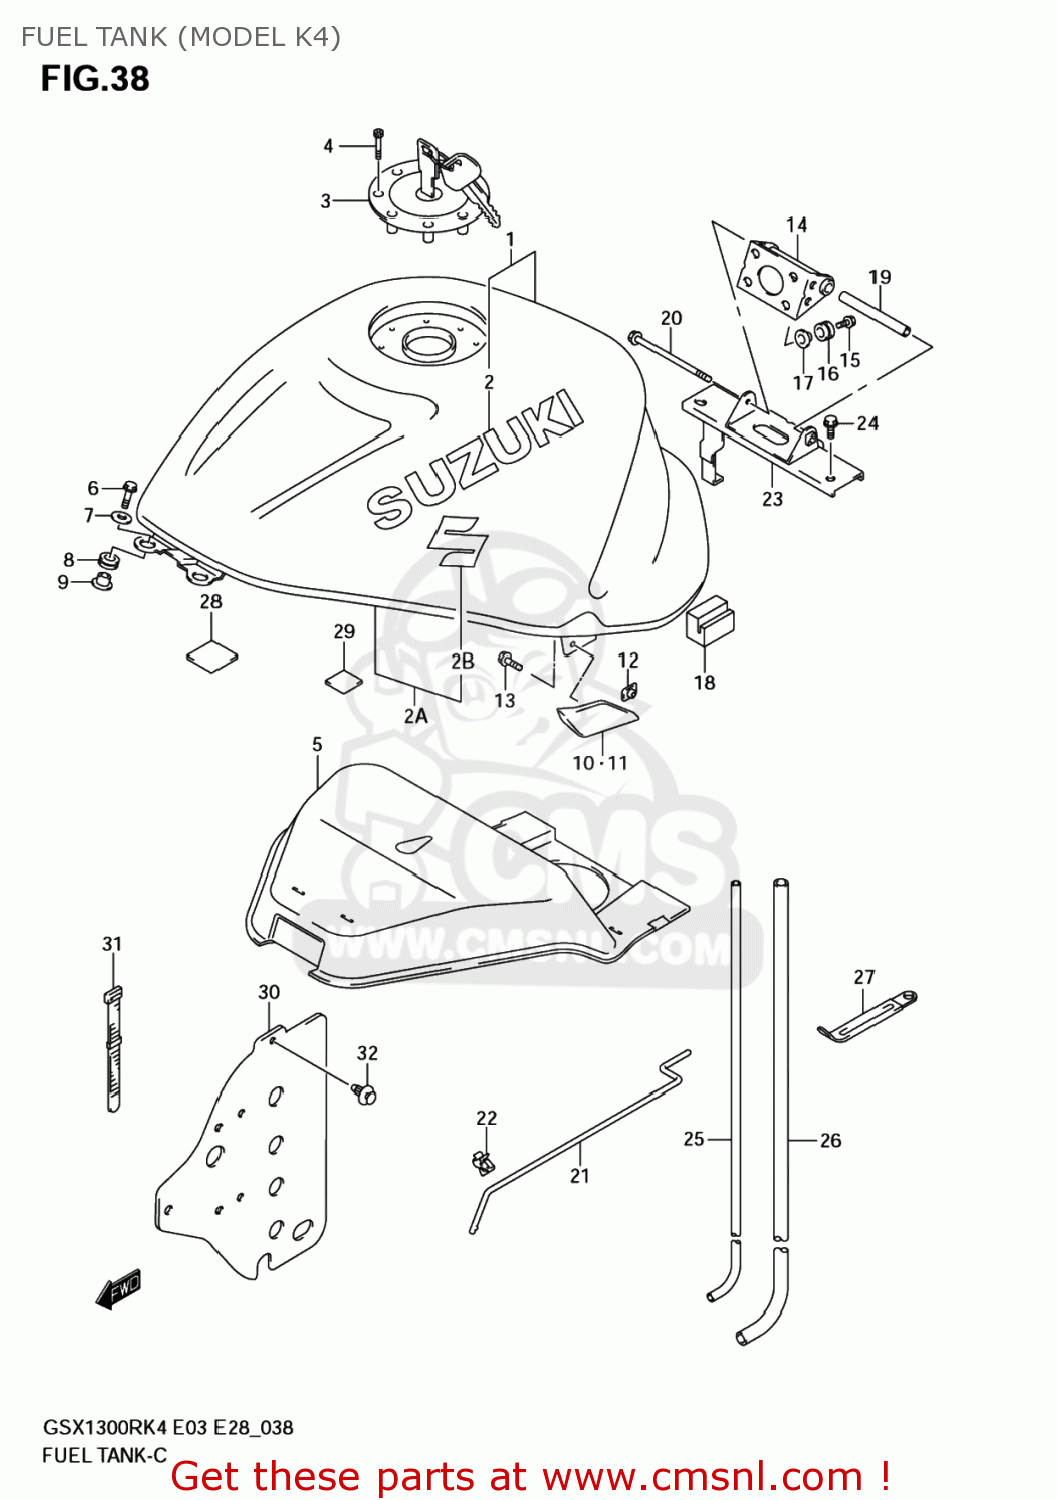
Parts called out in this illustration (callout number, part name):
1	TANK ASSY,FUEL
2	EMBLEM,FUEL TANK
2A	TANK ASSY,FUEL(RED)
2B	EMBLEM,S
3	CAP SET,FUEL TANK
4	BOLT(5X20)
5	SHIELD,FUEL TANK HEAT
6	SCREW(6X25)
7	WASHER(6.5X18X1.5)
8	CUSHION
9	WASHER
10	COVER,FUEL TANK SIDE,R
11	COVER,FUEL TANK SIDE,L
12	PLATE,FUEL TANK SIDE
13	SCREW 6X10
14	BRACKET,FUEL TANK RR NO.1
15	BOLT(6X20)
16	CUSHION
17	WASHER
18	CUSHION,FUEL TANK SIDE
19	SPACER,FUEL TANK RR
20	BOLT
21	STAY,FUEL TANK
22	CLAMP
23	BRACKET,FUEL TANK RR NO.2
24	BOLT
25	HOSE,FUELTANK BREATHER
26	HOSE(7X11X600)
27	CLAMP(L:80)
28	CUSHION
29	CUSHION,FUEL TANK COVER
30	SHEET,HEAT SHIELD RUBBER
31	CLAMP(L:165)
32	CLIP(BLACK)
